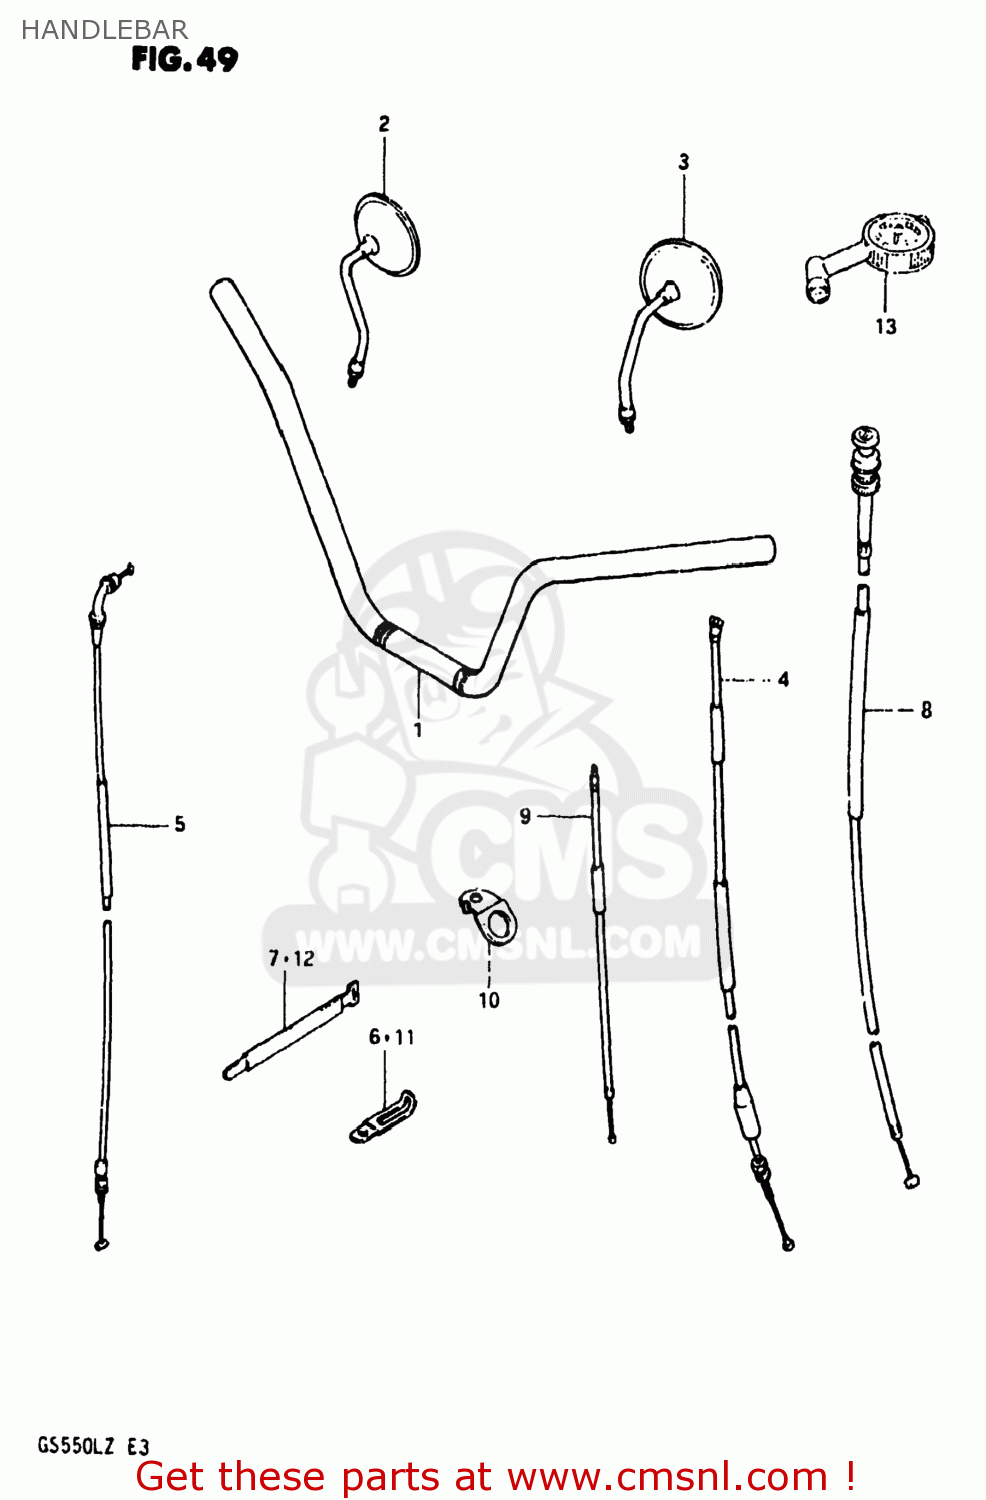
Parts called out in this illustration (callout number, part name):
1	HANDLEBAR
2	MIRROR ASSEMBLY,RIGHT
3	MIRROR ASSEMBLY,LEFT
4	CABLE,CLUTCH
5	CABLE ASSEMBLY,THROTTLE
6	CLAMP
7	CLAMP
8	CABLE ASSEMBLY,STARTER
9	CABLE COMP,STARTER
10	GUIDE,BRAKE HOSE
11	CLAMP
12	CLAMP
13	GAUGE ASSY,AIR PRESSURE
